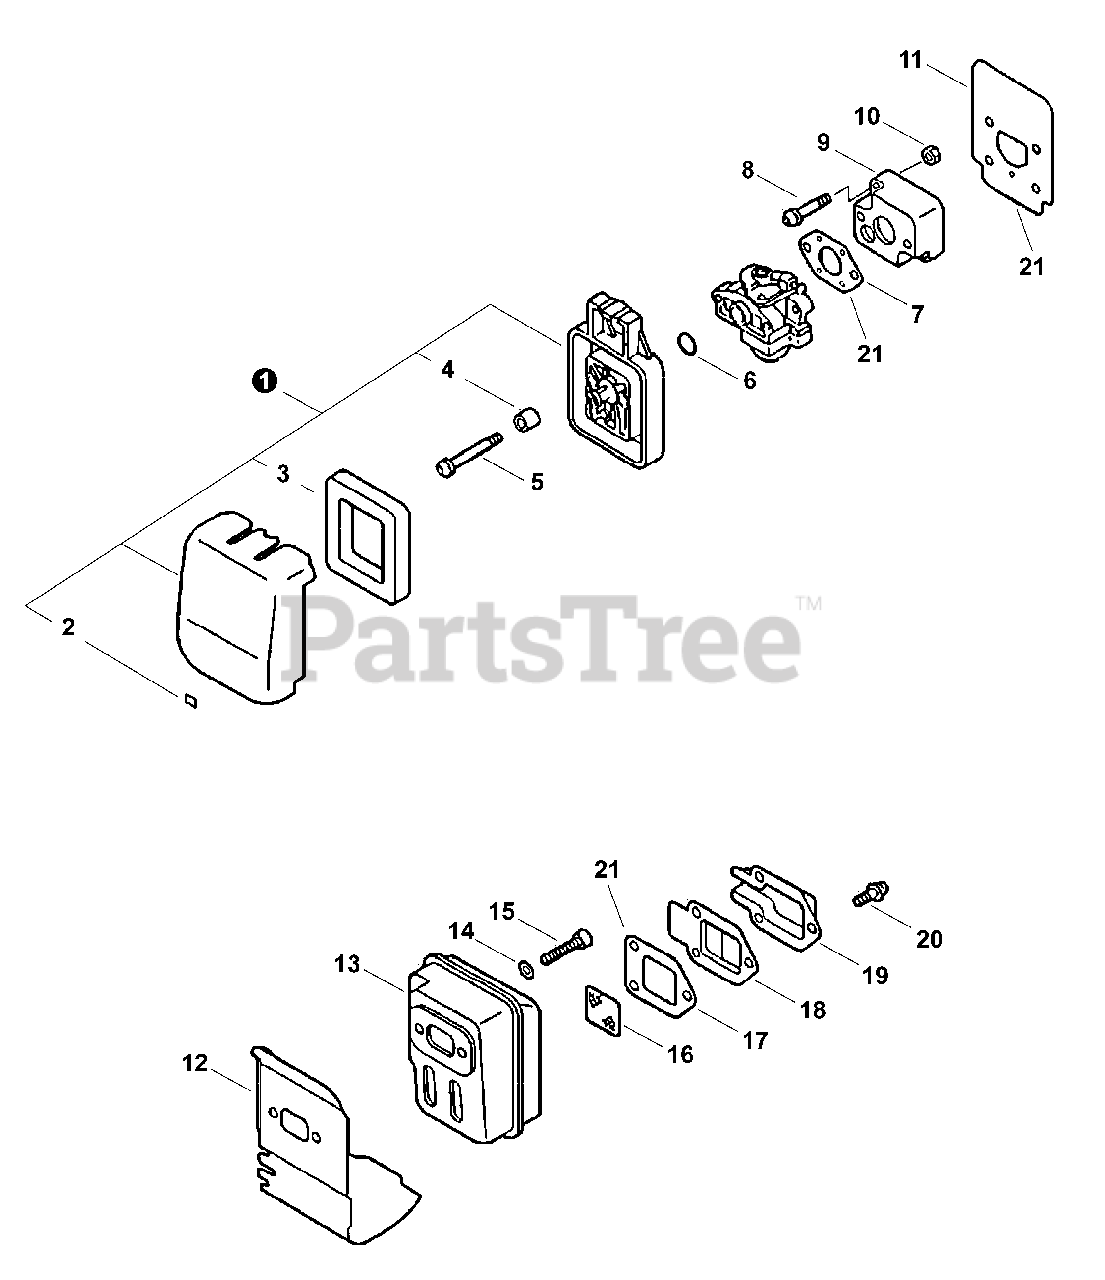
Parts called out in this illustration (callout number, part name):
1	FILTER ASSY, AIR
3	FILTER, AIR
4	SLEEVE
5	SCREW 5×64
6	O-RING 15
7	GASKET, INTAKE
8	SCREW 5×22
9	INSULATOR, INTAKE
10	NUT M5
11	HEAT SHIELD, INTAKE
12	GASKET, MUFFLER
13	MUFFLER
14	WASHER, FLAT 5.5×10×0.8
15	BOLT 5×55
16	SCREEN, SPARK ARRESTER
17	GASKET, EXHAUST
18	GUIDE, EXHAUST
19	GUIDE, EXHAUST
20	SCREW 4×10
21	GASKET KIT
